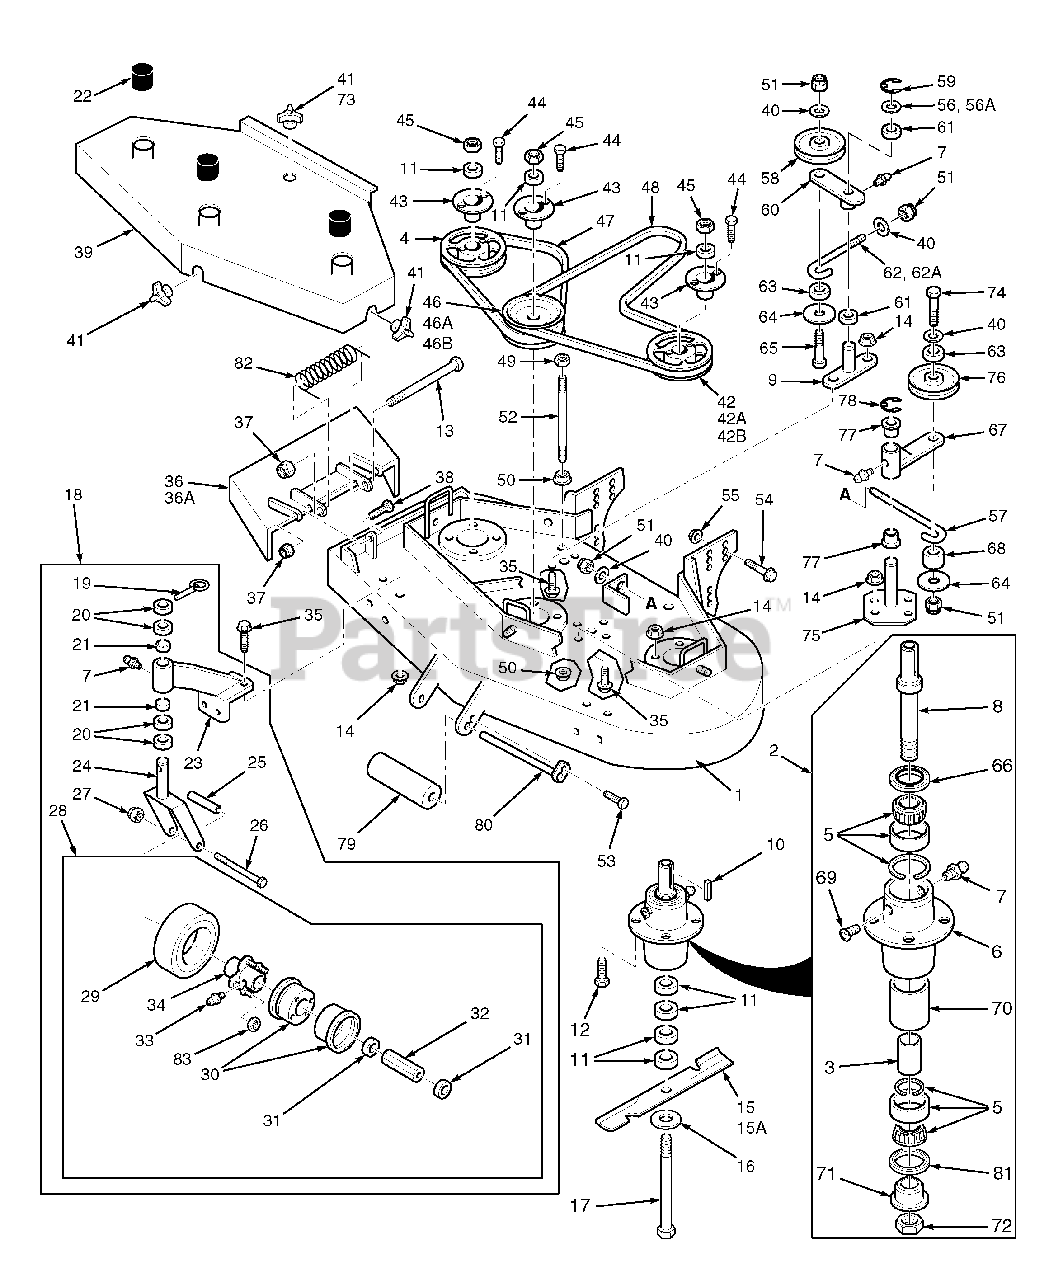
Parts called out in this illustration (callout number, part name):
1	Cutter Deck
2	Spindle Assembly
3	Spacer, Inside
4	Pulley
5	Tapered Bearing (Two)
6	Spindle Housing
7	Grease Fitting Str. 5/16
8	Spindle Shaft, Tapered Brng
9	Idler Pivot
10	Key, 1/4 x 1/4 x 2"
11	Spacer, Cutter Blade - Small
12	Bolt, 5/16-18 x 1-1/4" Hex Head
13	Bolt, 5/16-18 x 4-1/4" Hex Head
14	Serrated Flange Nut, 5/16-18
15	Cutter Blade 21"
15A	Cutter Blade 21 Hi Lift
16	Flatwasher,5/8" (.688 x 1.75 x .134)
17	Hex Head Bolt, 5/8-11 x 9-1/2"
18	Caster Assembly,
19	Quick Pin
20	Spacer, Caster Yoke, 1/2" thick
21	Bronze Bearing
22	Spindle Shield
23	Support Assembly,
24	Caster Yoke
25	Sleeve, Caster Wheel Bearing
26	Hex Hd Bolt, 1/2-13 x 5-1/2"
27	Elastic Stop Nut, 1/2-13
28	Wheel Assy.
29	Tire only, Caster Wheel
30	Rim Pair, Caster Wheel
31	Bearing Retainer, Caster Wheel
32	Roller Bearing, Caster Wheel
33	Grease Fitting 45 deg., 1/4-28
34	Hub Assembly,
35	Capscrew, 5/16-18 x 3/4"
36	Discharge Chute
36A	Discharge Chute
37	Nut, 5/16-18 Elastic Elastic Stop
38	Bolt, 5/16-18 x 1" Hex Head
39	Belt Cover
40	Flat Washer, 3/8" Special
41	Wing Nut, 3/8-16 (Large)
42	Pulley
42A	Pulley
42B	Pulley
43	Tapered Hub
44	Bolt, 1/4-20 x 3/4" Hex Head
45	Nut, 5/8-11 Hex
46	Pulley, Double
46A	Pulley, Double
46B	Pulley, Double
47	Belt, RH Blade Drive
48	Belt, Blade Drive
49	Nut, 3/8-16, Nut Centerlock
50	Nut, 3/8-16, Serrated Flange
51	Nut, 3/8-16 Elastic Stop
52	Support, Belt Cover
53	Bolt, 5/16-18 x 1/2" Hex Head
54	Cpscrw,7/16-14 x 1"Ser Flng H Hd
55	Nut, 7/16-14 Serrated Flange
56	Flat Washer 3/4" Special
56A	Flat Washer 3/4" Special
57	J-Hook
58	Idler Pulley, "V" Groove
59	Retaining Ring, 3/4" Ext."E"
60	Idler Arm Assy.
61	Bronze Bearing
62	J-Rod, Idler Pulley
62A	J-Rod, Idler Pulley
63	Spacer, J-Rod
64	Washer, 3/8 x 1-1/2 x 16 ga.
65	Bolt, 3/8-16 x 2-1/4" Hex Head
66	Seal, Cutter Spindle
67	Idler Arm Assy
68	Spacer, J-Rod
69	Relief Fitting, Cutter Spindle
70	Spacer, Outside, Cutter Spindle
71	Spindle Bushing
72	Nut, Cutter Spindle
73	Wing Nut, 3/8-16 (Small) Top Side
74	Bolt, 3/8-16 x 3-1/2" Hex Head
75	Idler Pivot
76	Idler Pulley, Belt Clutch
77	Bronze Bearing
78	Retaining Ring
79	Guide Roller
80	Roller Shaft
81	Seal, Cutter Spindle
82	Spring, Chute Return
83	Nut, 3/8-24 Tapered
NS	Inner Tube only, Caster Wheel
